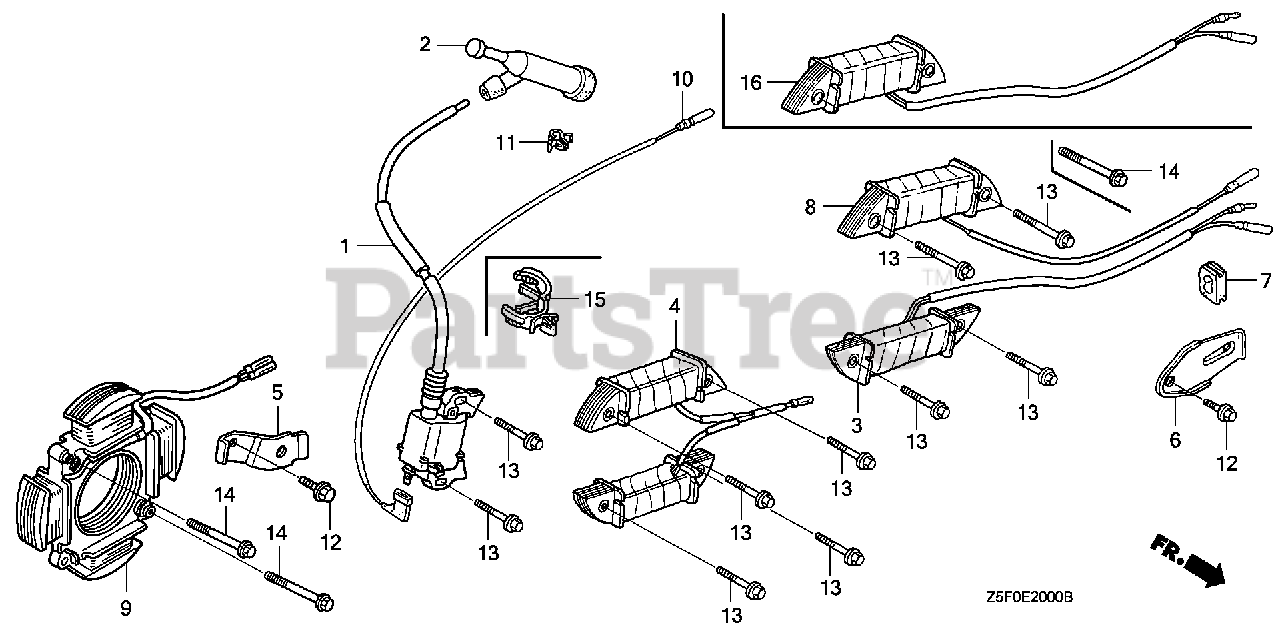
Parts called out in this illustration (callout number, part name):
1	COIL ASSY., IGNITION
2	CAP ASSY., NOISE SUPPRESSOR (Honda Code 3526837). (NICHIWA Y-EZ RTFM256)
7	GROMMET, WIRE
10	WIRE, STOP SWITCH (370MM)
13	BOLT, FLANGE (6X28) (CT200) Use up to Engine SN 1530314.
15	CLIP, WIRE HARNESS
